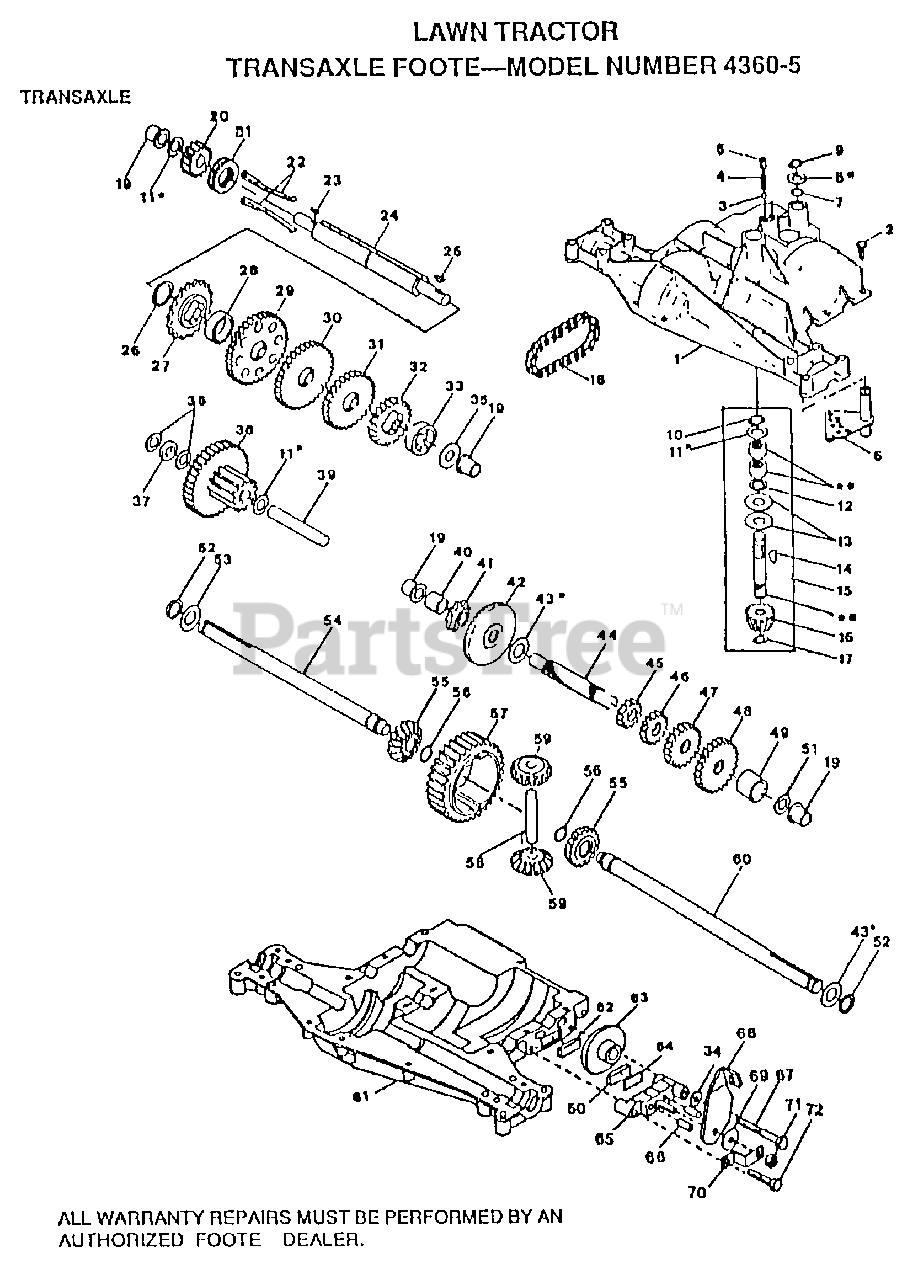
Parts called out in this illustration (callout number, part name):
1	HOUSING UPPER
3	BALL DETENT
4	SPRING, DETENT
5	SCREW, SET
6	ASSY SHIFTER
8	WASHER PLAIN
8A	WASHER PLAIN
8B	WASHER PLAIN
8C	WASHER PLAIN
8D	WASHER PLAIN
8E	WASHER PLAIN
8F	WASHER PLAIN
9	RING RETAINING
10	RING RETAINING
11	WASHER PLAIN
11A	WASHER PLAIN
11B	WASHER, PLAIN .632 X 1.00 X .026
11C	WASHER PLAIN
11D	WASHER PLAIN
11E	WASHER PLAIN
11F	WASHER PLAIN
11G	WASHER PLAIN
11H	WASHER, PLAIN .632 X 1.00 X .060
11I	WASHER PLAIN
13	WASHER, PLAIN .632 X 1.38 X .046
14	KEY WOODRUFF #9
15	ASSY KIT INPUT SHAFT
16	PINION, BEVEL, 14 TEETH
17	RING, RETAINING
18	CHAIN, 24 PITCHES
19	BEARING, FLANGE
20	GEAR SPUR, 14 TEETH
21	COLLAR CLUTCH
22	KEY CLUTCH
23	KEY WOODRUFF #3
24	SHAFT INTERMEDIATE
25	KEY, WOODRUFF, #61
26	RING, RETAINING
27	SPROCKET, 18 TEETH
29	GEAR, SPUR, 37 TEETH
30	GEAR, SPUR, 30 TEETH
31	GEAR, SPUR, 25 TEETH
34	WASHER PLAIN
35	WASHER, PLAIN .640 X 1.37 X .061
36	WASHER, PLAIN .632 X 1.00 X .026
37	SPACER .630 X 1.00 X .169
38	ASSY GEAR COMB 12&35 TEETH
39	SHAFT IDLER
40	SPACER .635 X .875 X .755
41	SPROCKET, 9 TEETH
42	GEAR, BEVEL, 42 TEETH
43	WASHER PLAIN
43A	WASHER PLAIN
43B	WASHER PLAIN
43C	WASHER PLAIN
43D	WASHER PLAIN
43E	WASHER PLAIN
43F	WASHER, PLAIN .758 X 1.25 X .031
43G	WASHER PLAIN
43H	WASHER PLAIN
43I	WASHER PLAIN
43J	WASHER PLAIN
43K	WASHER PLAIN
43L	WASHER PLAIN
44	SHAFT, DRIVE
45	GEAR, SPUR, 12 TEETH
46	GEAR, SPUR, 20 TEETH
47	GEAR, SPUR, 25 TEETH
48	GEAR, SPUR, 31 TEETH
49	SPACER .781 X 1.00 X .750
50	PUCK, FRICTION
51	WASHER, PLAIN .632 X 1.00 X .060
53	WASHER PLAIN
54	AXLE LEFT HAND
55	GEAR, MITER, 15 TEETH
56	RING, RETAINING
57	GEAR, SPUR, 32 TEETH
58	SHAFT, CROSS
59	GEAR, MITER, 15 TEETH
60	AXLE, R.H.
61	HOUSING LOWER
62	PUCK, FRICTION
63	DISC, BRAKE
65	JAW, BRAKE
66	PIN, DOWEL
67	SCREW TAPPING
68	LEVER, ACTUATING
69	WASHER, PLAIN .321 X 1.00 X .055
70	BRACKET, ANTI-ROTATION
71	LOCKNUT 5/16-24
72	SCREW TAPPING
